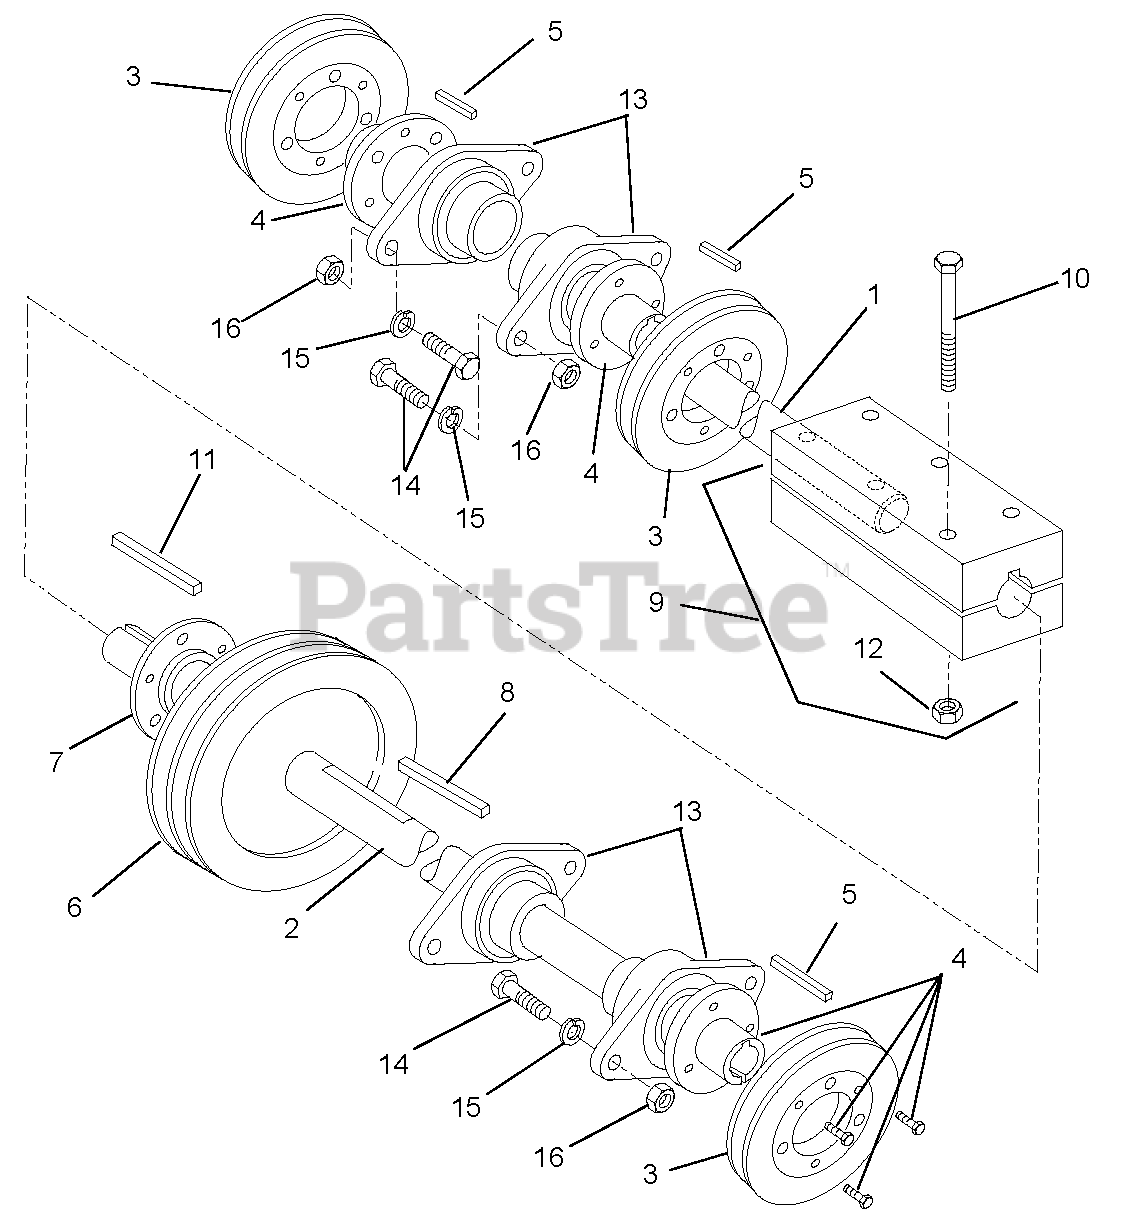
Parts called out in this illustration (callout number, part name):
1	Jackshaft, Right Hand Rear (895435)
2	Jackshaft, Left Hand Rear (895435)
3	Pulley, Taper Lock
4	Bushing, Split Tapered
5	Key, Square .25 x .25 x 1
6	Pulley, 2-Belt 6.6 PD
7	Bushing, Split Tapered
8	Key .25 x .25 x 3
9	Assembly, Jackshaft Coupling
10	Cap Screw, Hex Head .312-18 x 2.5
11	Key .25 x .25 x 5
12	Nut, Nylock Hex .312-18
13	Flange, Bearing 2-Bolt
14	Cap Screw, Hex Head .437 x 1.25
15	Washer, Lock .437
16	Nut, Hex .437
